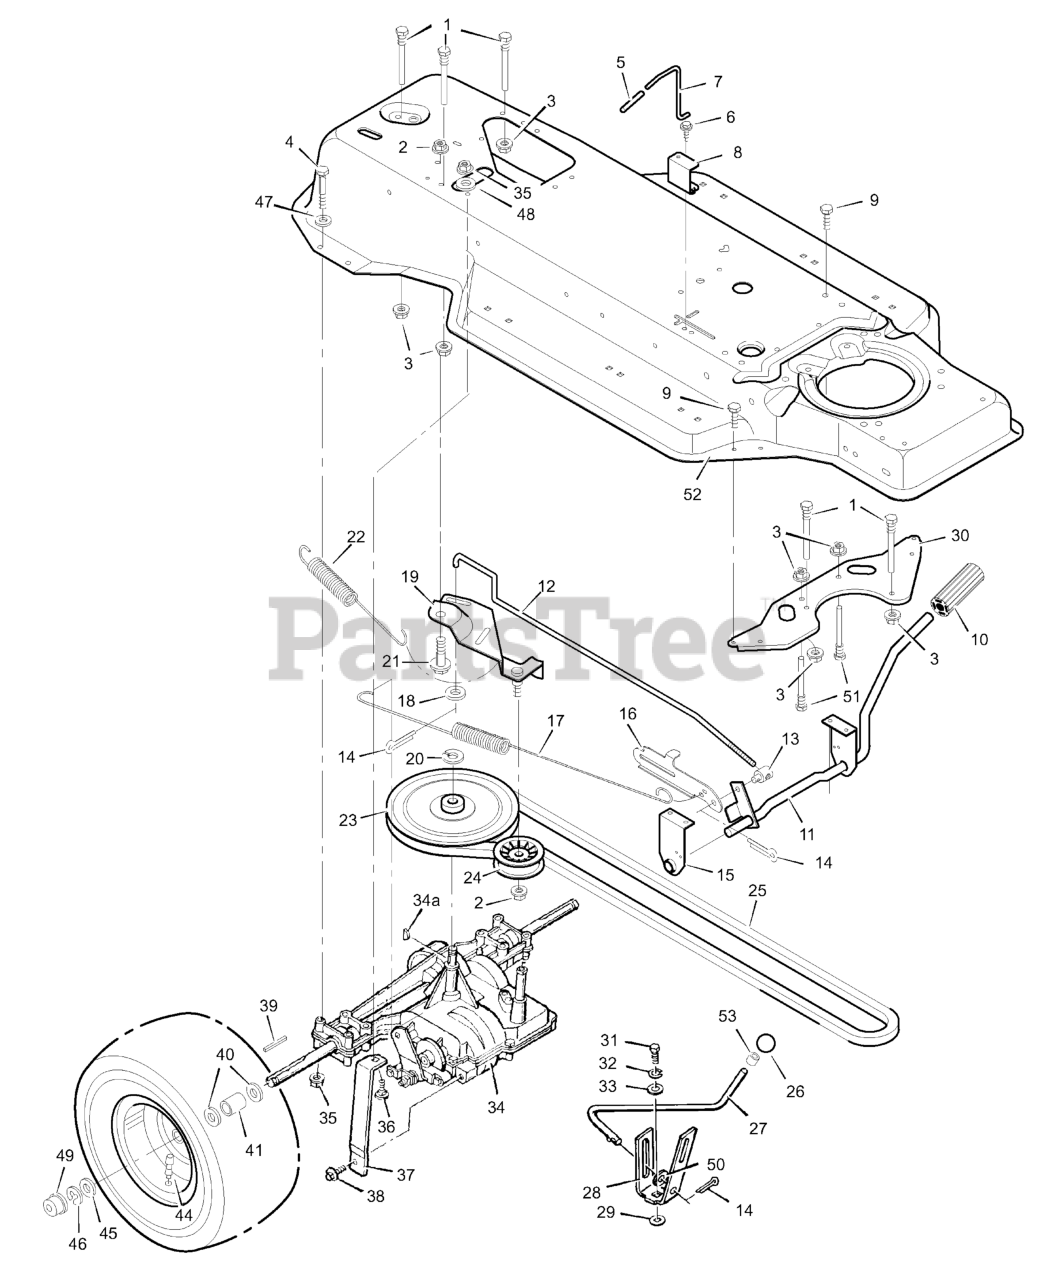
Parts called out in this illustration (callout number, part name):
1	Guide, Belt
2	Locknut, Flange
3	Nut, Flange
4	Bolt, Hex
7	Rod, Control
8	Guide, Bracket
10	Clutch and Brake Pedal
11	Lever Assembly
12	Rod, Clutch
13	Nut, Adjustable
14	Pin, Cotter
15	Bracket, Support
16	Latch, Park Brake
17	Spring, Brake Extension
18	Washer
19	Bracket Assembly, Idler
20	Ring, Retainer
21	Bolt, Shoulder
22	Spring, Drive Extension
23	Pulley, Motion Drive
24	Pulley, Backside Idler
25	Belt, Motion Drive
26	Knob, Shift Lever
27	Lever, Shift
28	Yoke, Shift
30	Plate, Belt Guide
31	Bolt, Hex
32	Lockwasher
34	Transaxle, Peerless **
34A	Woodruff Key No. 9
35	Nut, Flange
36	Bolt, Carriage
37	Support, Transaxle
39	Key, Square
41	Spacer, Transaxle
43	Wheel & Tire Assembly
44	Stem, Valve
47	Washer
49	Hub Cap
50	Washer
51	Guide, Belt
52	Frame Assembly
53	Ring, Tolerance
